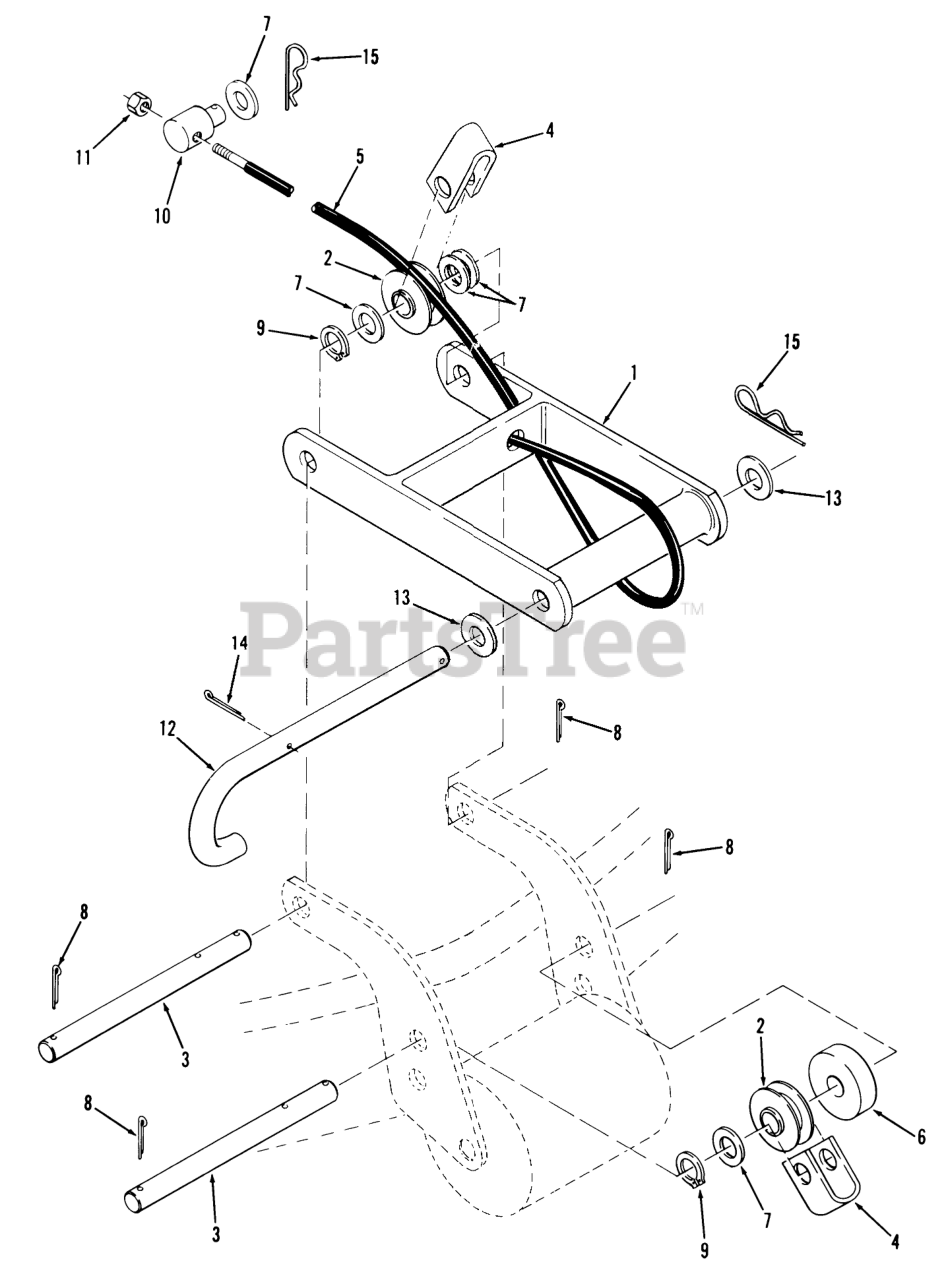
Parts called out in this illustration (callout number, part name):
1	Front Housing Mount (42 in./107 cm)
1	Front Mount
2	ROLLER-CABLE
3	Rod
4	STRAP-CABLE
5	ASSY-CABLE 36IN&42IN
6	SPACER
7	Washer
8	Pop Rivet
9	GRIP RING
10	TRUNNION-CLUTCH ROD
11	Nut
12	Front Link Pin
13	Washer
15	Hairpin Cotter
